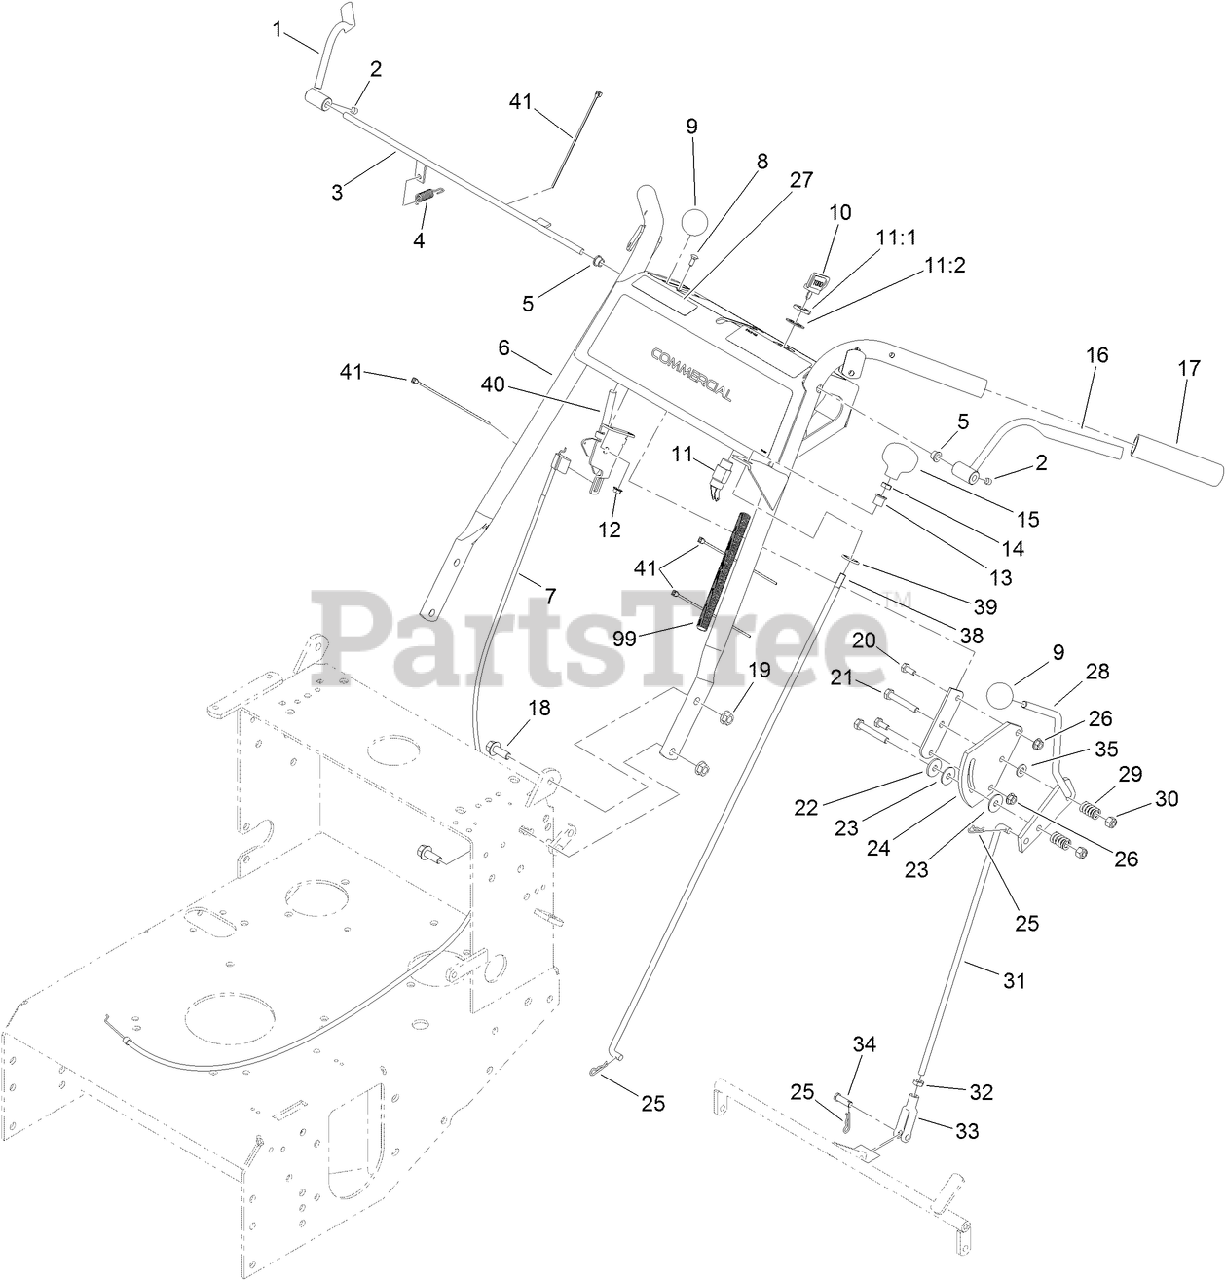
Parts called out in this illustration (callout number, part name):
1	RH OPERATOR PRESENCE CONTROL LEVER ASM
2	SCREW-SET
3	ROD-CONTROL, OPERATOR PRESENCE
4	SPRING-EXTENSION
5	BUSHING-NYLON
6	HANDLE ASM
7	CABLE-CONTROL, THROTTLE
8	BOLT-CARR
9	KNOB-BALL
10	KEY-IGNITION
11	SWITCH-ON / OFF
11:1	NUT-HH
11:2	WASHER-TOOTH, INTERNAL
12	NUT-LOCK, FLANGE
13	Bearing-Nylon
14	NUT-JAM
15	Knob-Push / Pull
16	LH OPERATOR PRESENCE CONTROL LEVER ASM
17	GRIP-FOAM
18	SCREW-HHF
19	NUT-HF
20	SCREW-HH
21	SCREW-HH
22	Washer-Friction
23	Washer-Friction
24	PLATE-LEVER, SHIFTER
25	PIN-COTTER
26	NUT-HF
27	DECAL-ARRESTER, SPARK
28	LEVER-SHIFT
29	SPRING-COMPRESSION
30	NUT-LOCK, NI
31	Rod-Control, Speed
32	NUT-JAM
33	YOKE-ADJUSTABLE
34	PIN-CLEVIS
35	WASHER-PLAIN
38	Linkage-Blade
39	NUT-PUSH
40	LEVER-CONTROL
41	TIE-CABLE
99	HARNESS-WIRING
